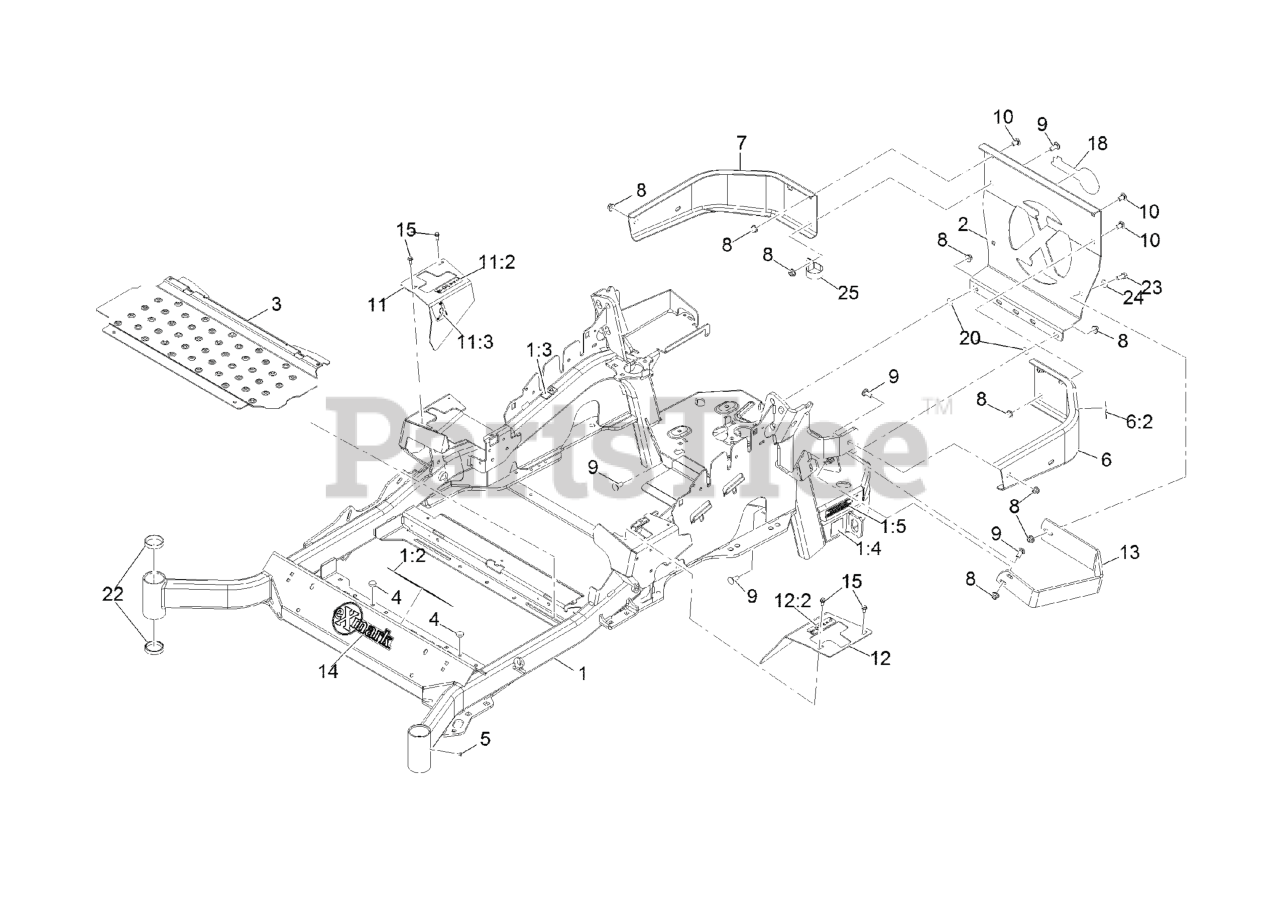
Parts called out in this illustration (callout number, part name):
1	MAINFRAME ASM
1:2	DECAL-DANGER
1:3	DECAL-WARNING
1:4	DECAL-HAZARD, PINCHED FINGER
1:5	DECAL-ARRESTOR, SPARK
2	PLATE,REAR GUARD
6	LH BUMPER ASM
6:2	DECAL-WARNING
7	BUMPER-RH
8	NUT-HF, NI
9	SCREW-CARR
10	SCREW-CARR
11	RH MOTION CONTROL COVER ASM
11:2	DECAL-CONTROL, MOTION
11:3	DECAL-PARK BRAKE, CE
12	LH MOTION CONTROL COVER ASM
12:2	DECAL-CONTROL, MOTION
13	GUARD-MUFFLER
14	DECAL-EXMARK
15	SCREW-HWH
20	NUT-PUSH
22	CUP-BEARING
23	SCREW-HH
24	WASHER-FLAT
25	CLAMP-R
